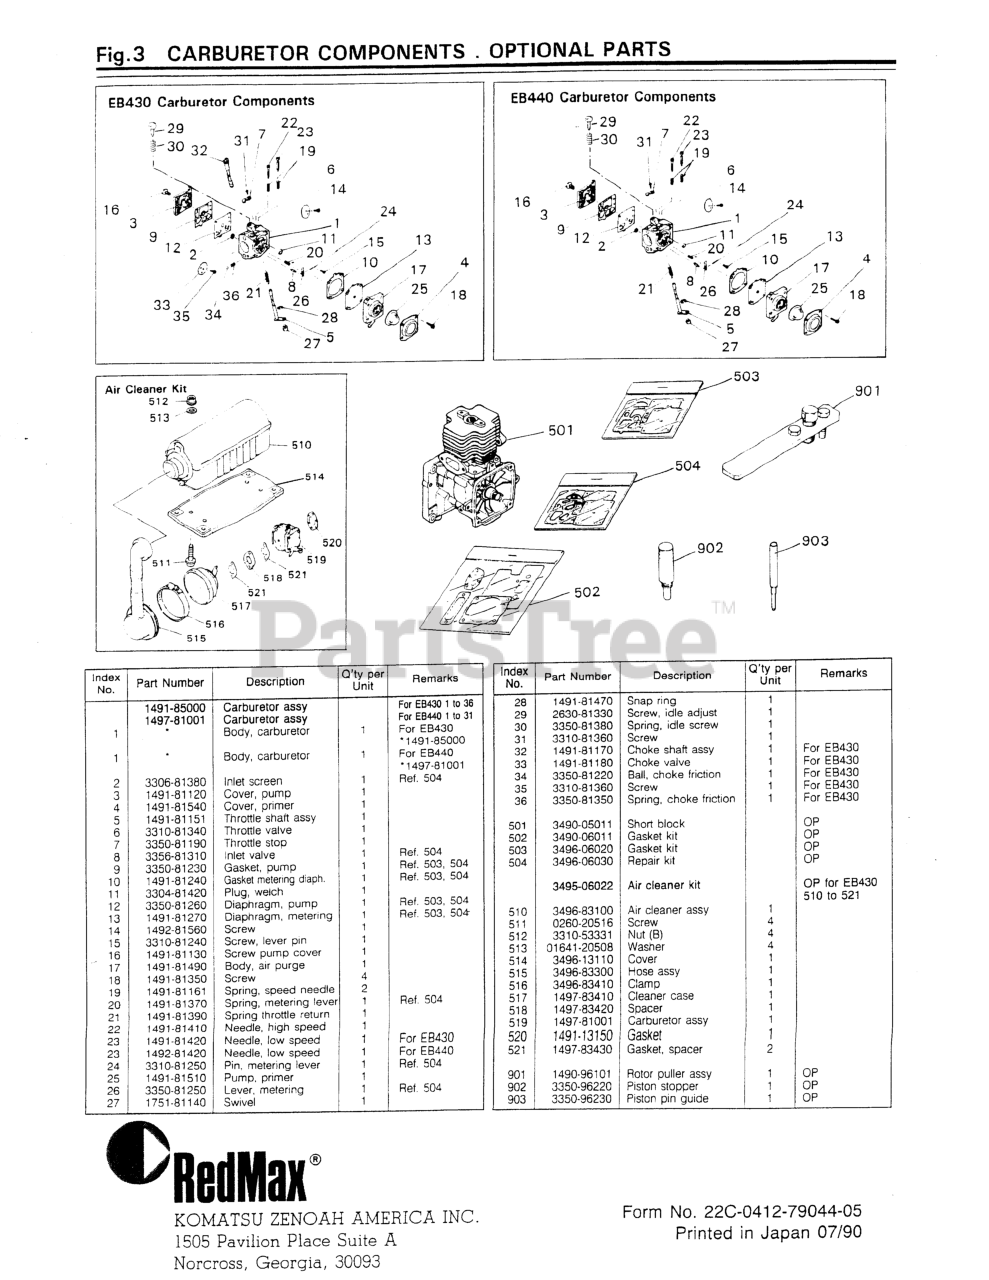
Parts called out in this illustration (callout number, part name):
3	COVER, PUMP
4	COVER, PUMP
5	SHAFT ASSEMBLY
7	THROTTLE STOP
8	VALVE, INLET
9	KIT ONLY
10	KIT ONLY
12	KIT ONLY
18	SCREW (USE 1480-81520)
20	KIT ONLY
21	SPRING
23	NEEDLE, IDLE
24	PIN, METERING LEVER
25	PUMP, PRIMER
26	KIT ONLY
30	SPRING, IDLE
32	SHAFT ASSEMBLY
33	VALVE, CHOKE
34	BALL, FRICTION
36	SPRING
501	BLOCK, SHORT (RPLS -05010)
502	GASKET KIT (RPLS -06010)
503	EB430/40 DIA/GASK KIT
504	REBUILD KIT, EB430/440
510	CLEANER, AIR
511	SCREW, M5 x 16
512	NUT (B)
513	WASHER, M5 X .8
516	CLAMP
517	CASE, CLEANER
901	PULLER ASSEMBLY (TOOL)
902	STOPPER (TOOL) (RPLS 3320-9641
903	GUIDE (TOOL)
NI	AIR CLEANER KIT
